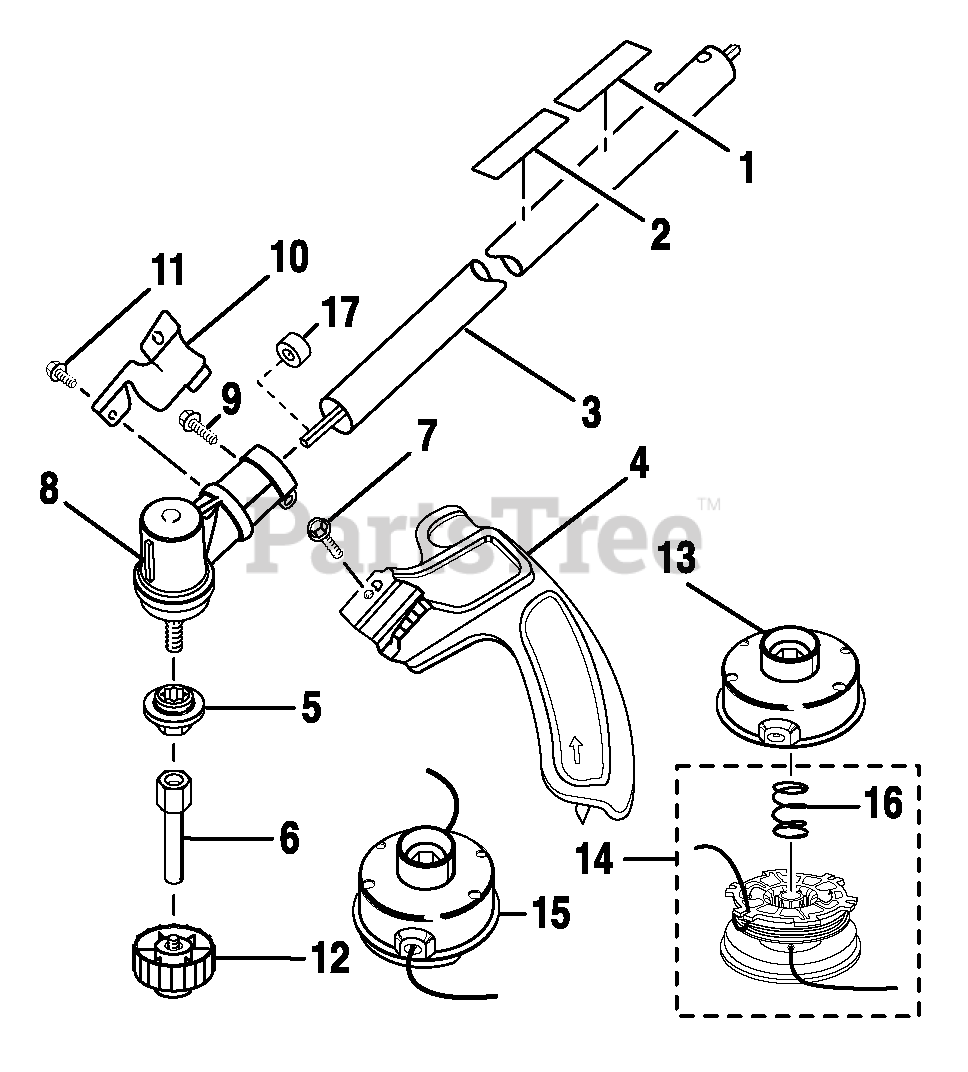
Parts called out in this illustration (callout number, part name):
1	Expand-it Label
2	Warning Decal
3	Straight Shaft Assembly
4	Grass Deflector Assembly
5	Washer
6	Shaft Adapter
7	Screw (1/4-20 x 1-1/4 in.)
8	Gear Head
9	Screw (1/4-20 x 1-1/4 in.)
11	Screw (10-24 x 5/8 in.)
12	Spool Retainer (Red)
13	Housing and Eyelet
14	Spool and String (.095 in.) w/Spring
15	Complete String Head (.095 in.)
17	Spacer
